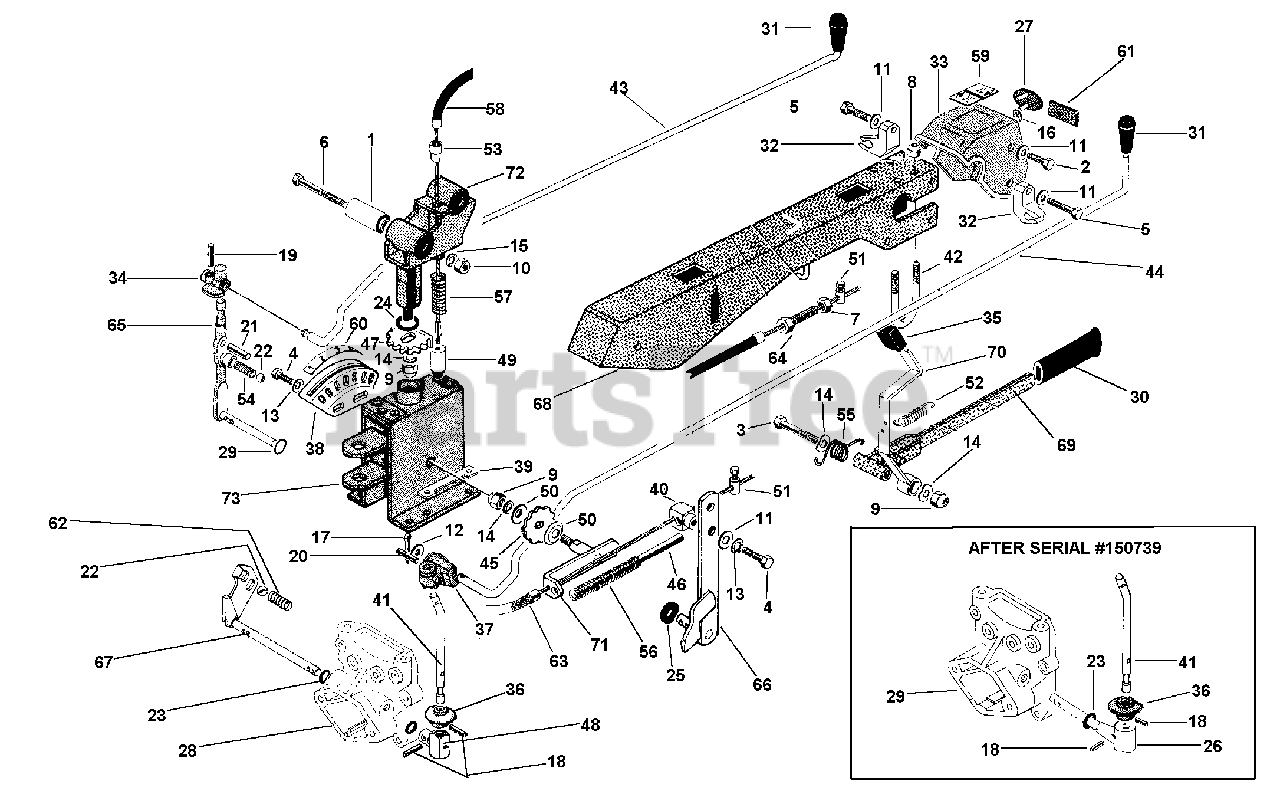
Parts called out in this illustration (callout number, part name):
1	SILENTBLOCK
2	SCREW M8 X 16
3	SCREW TE M10 X 90
4	SCREW M8 X 12
5	SCREW M8 X 35
6	SCREW TE M12 X 95
8	NUT, SELF LOCKING M8
9	NUT, SELF LOCKING M10
10	NUT, SELF LOCKING M12
11	WASHER, FLAT 8.4
12	WASHER P10.5 X 18
13	WASHER, LOCK 8.4
14	WASHER, LOCK 10.5
15	WASHER, LOCK 13
16	WASHER, LOCK FOR PINS
18	LOCKING PIN 4 X 20 SPIRAL
19	PIN, LOCKING SW 3 X 22 SPIRAL
20	LOCKING PIN 4 X 24 SPIRAL
21	LOCKING PIN SPIRAL
22	BALL 15/32 RIV RB-11.906
23	O-RING 115 11.91 X 2.62
24	O-RING 4112 28.17 X 3.53
25	SEAL, OIL 12 X 19 X 5 STANDARD
26	PTO CONTROL PIN D = 25
28	REAR COVER, 18MM PTO SHAFT
29	REAR COVER, 25MM PTO SHAFT
32	SUPPORT CONTROL ROD CUT
33	STEERING COLUMN INTERM. PANEL
34	GEARBOX ARTICULATION
35	KNOB REDUCTION UNIT LEVER
36	PTO STOP RING
37	PTO ARTICULATION
38	GEARBOX SELECTOR
39	REVERSE SPEED LEVER DOG
40	REVERSE BLOCK
41	PTO CONTROL LEVER
42	HANDLEBAR U-BOLT
43	GEARBOX CONTROL ROD
44	PTO CONTROL ROD
45	REVERSE GEAR
47	BENDED REVERSER GEAR
49	PUSH ROD D = 8
50	PROTECTION END D 32
51	CLAMP, CABLE
52	LEVER RETURN SPRING
55	HANDLEBAR RELEASE SPRING
56	REVERSER SPRING
57	PUSH ROD SPRING
58	STEERING COLUMN CABLE
59	STEERING COLUMN STICKER
60	SPEED STICKER
61	STICKER 605
63	CABLE,REVERSER
64	ADJUSTING SCREW
65	GEARBOX LEVER
66	REVERSER LEVER
68	STEERING COLUMN
69	HANDLEBAR RELEASE LEVER
70	STEERING COLUMN LOCKING LEVER
71	REVERSER POSITION LEVER
72	STEERING COLUMN COUPLING
73	STEERING COLUMN SUPPORT
